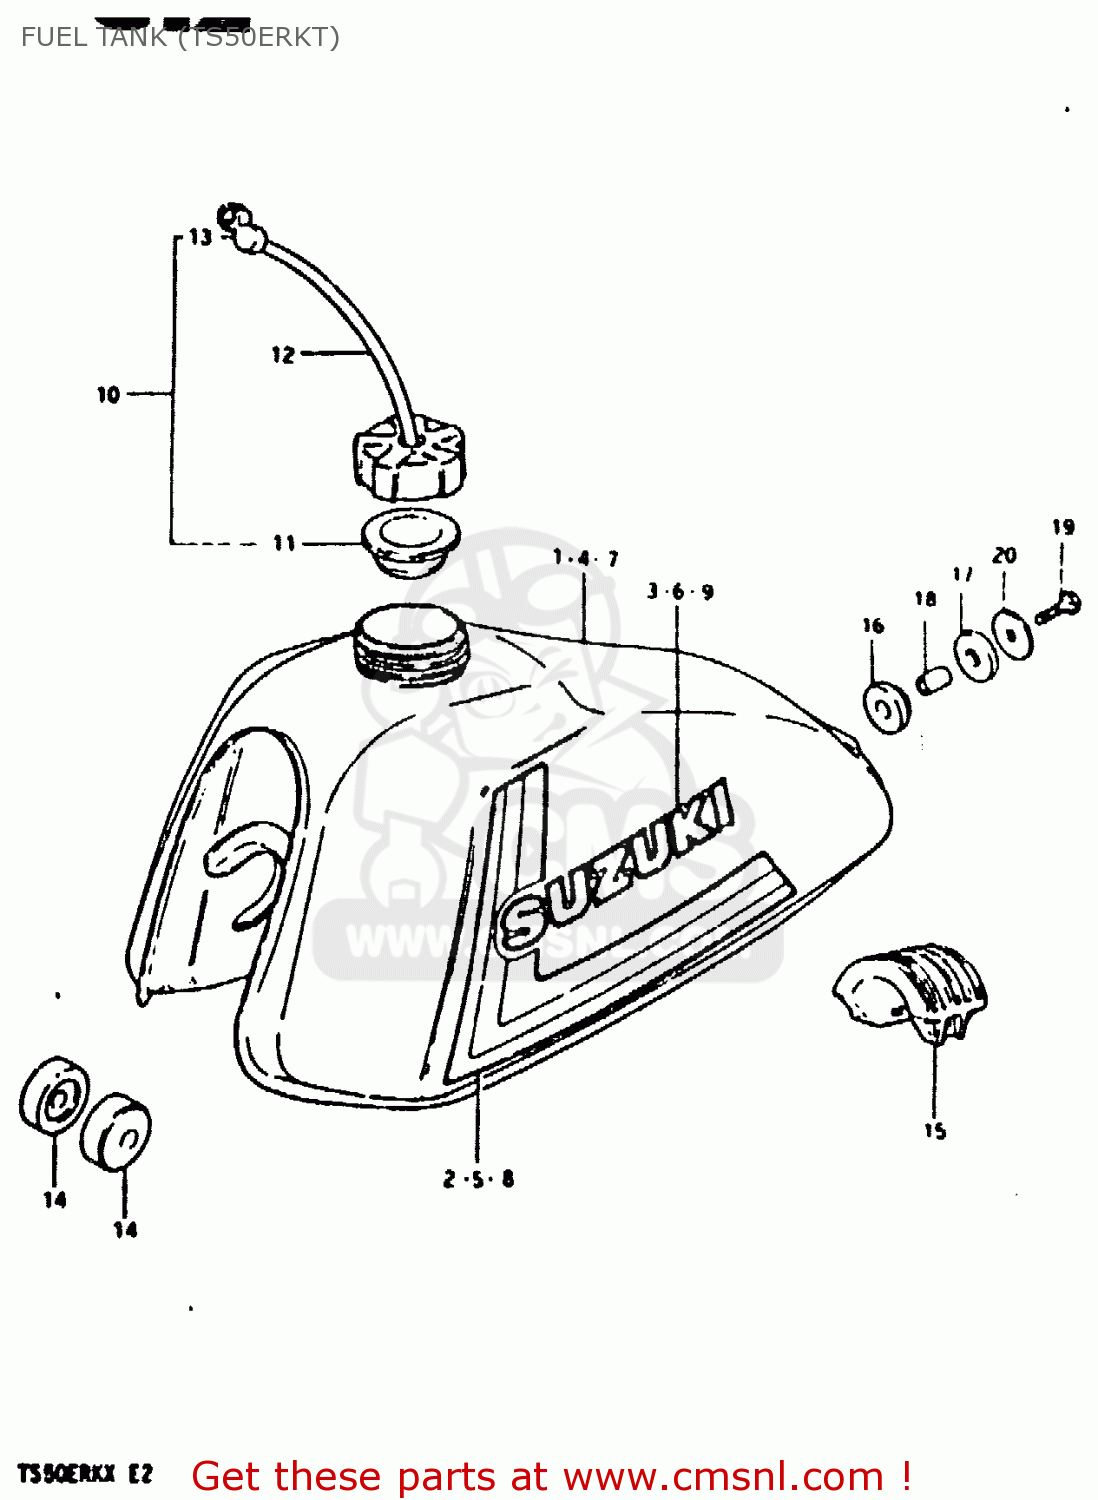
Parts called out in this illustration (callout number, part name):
1	TANK, FUEL (RED)
2	TAPE SET
3	EMBLEM
4	TANK, FUEL (BLUE)
5	TAPE SET
6	EMBLEM
7	TANK, FUEL (WHITE)
8	TAPE SET
9	EMBLEM(BLACK)
10	CAP SET,FUEL TANK
11	GASKET,FUEL TANK CAP (NAS)
12	HOSE
13	CLAMP,FUEL TANK BREATHER HOSE
14	CUSHION
15	CUSHION,FUEL TANK
16	CUSHION
17	CUSHION
18	SPACER(8.5X12X19)
19	BOLT (8X30)
20	WASHER (8.5X29X1.6)
